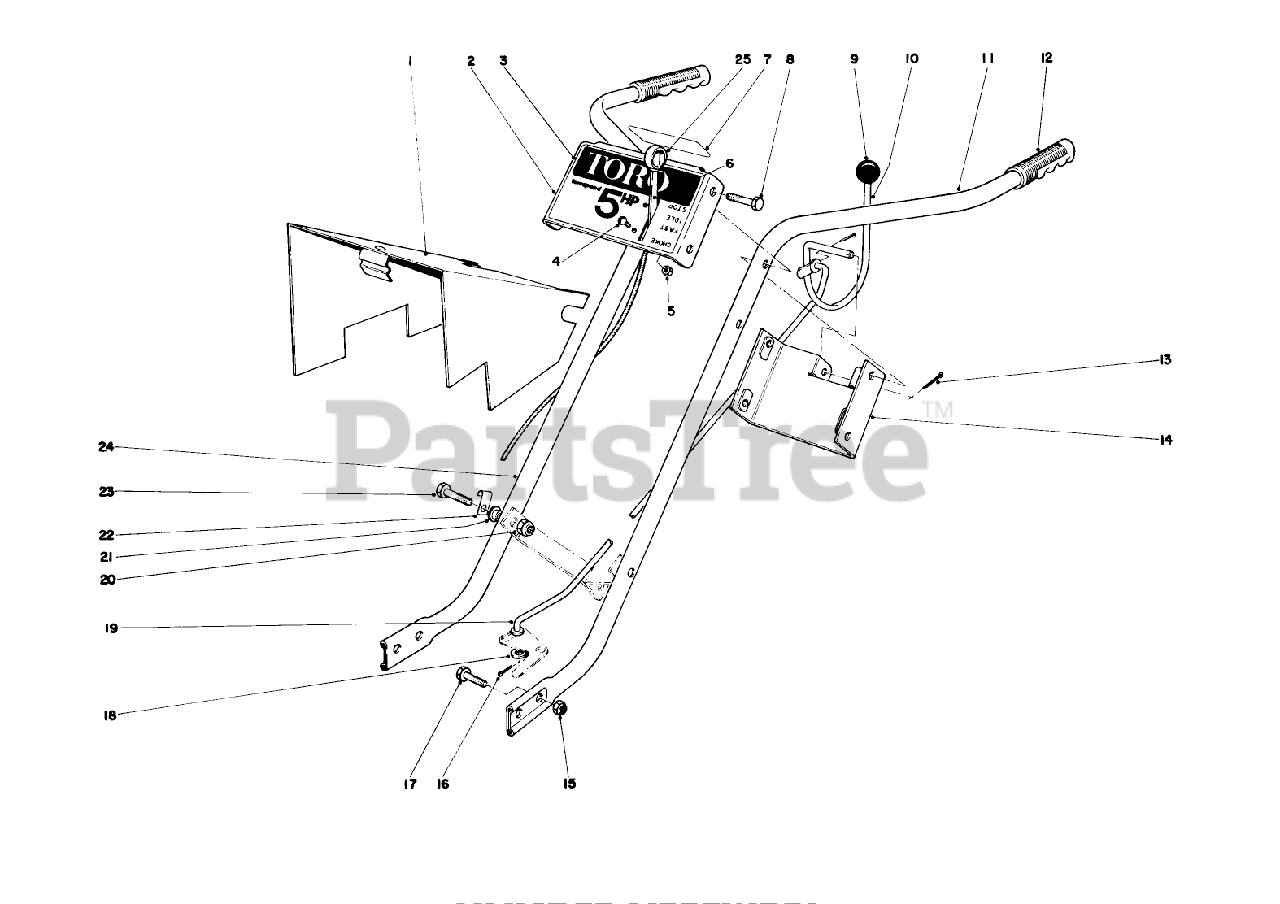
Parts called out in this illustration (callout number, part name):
2	Control Plate
3	Decal, Control
4	SCREW-PPH
5	NUT-KEPS
6	Throttle Control
7	Decal Clutch
8	SCREW-HH
9	KNOB-CONTROL
13	PIN-COTTER
14	Handle Brace
15	NUT-LOCK, CONE
16	PIN-COTTER
17	SCREW-HH
18	WASHER-FLAT
20	NUT-LOCK, CONE
21	Spacer
23	SCREW-HH
